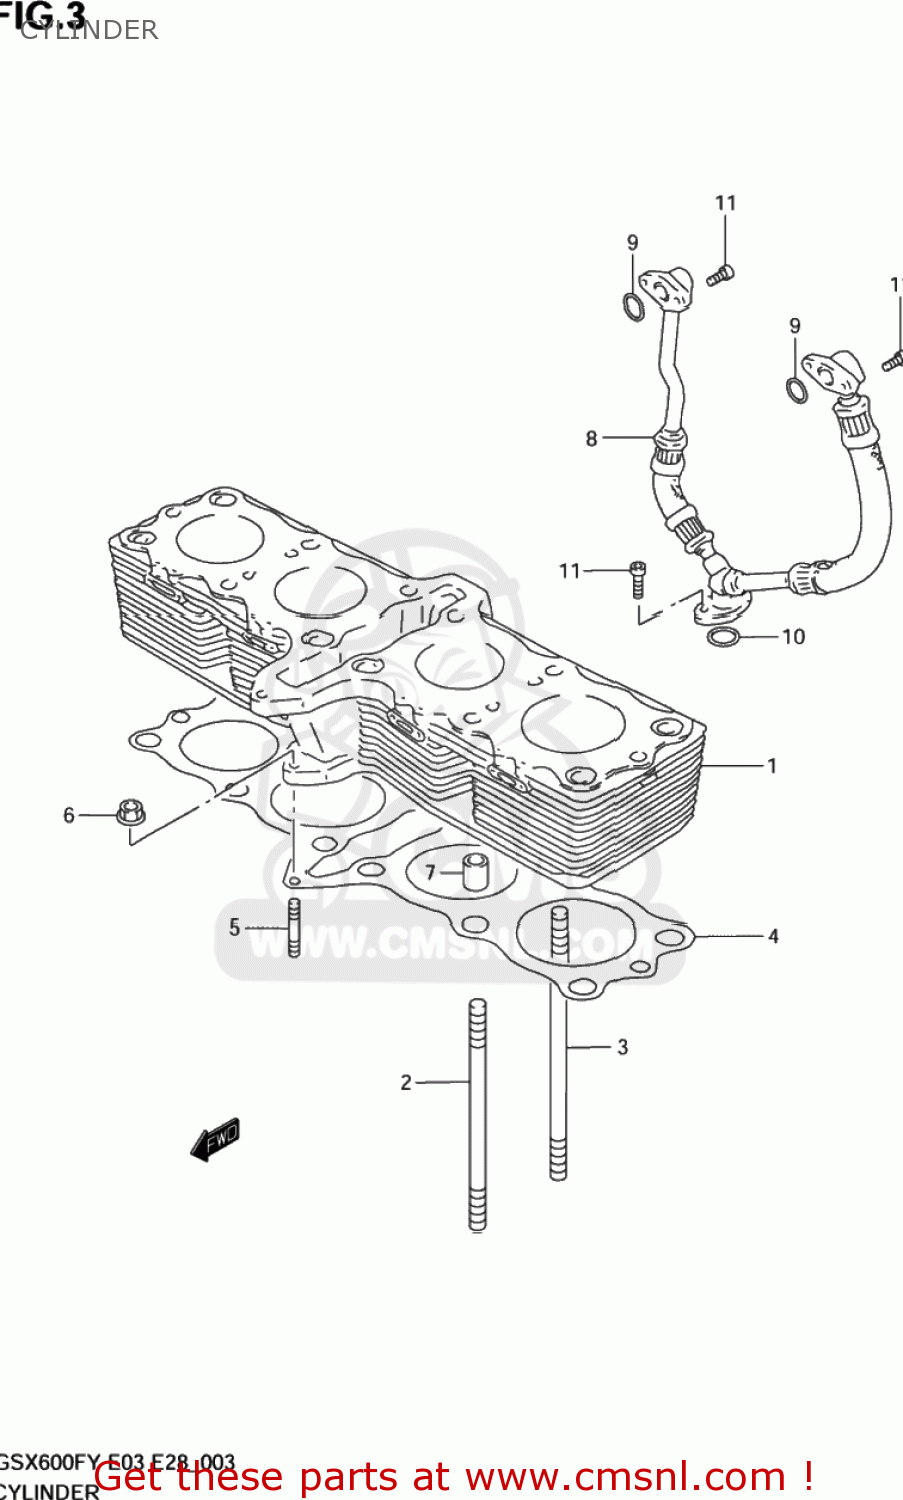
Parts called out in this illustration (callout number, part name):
1	CYLINDER
2	STUD BOLT (L:150)
3	BOLT,STUD
4	GASKET,CYLINDER (NAS)
5	STUD,M6X1X32
6	NUT
7	PIN(13X10.4X20)
8	HOSE,OIL HEAD COOLER
9	O RING(D:2.5,ID:13.8)
10	O RING(D:2.4,ID:15.8)
11	BOLT,OIL FILLE
